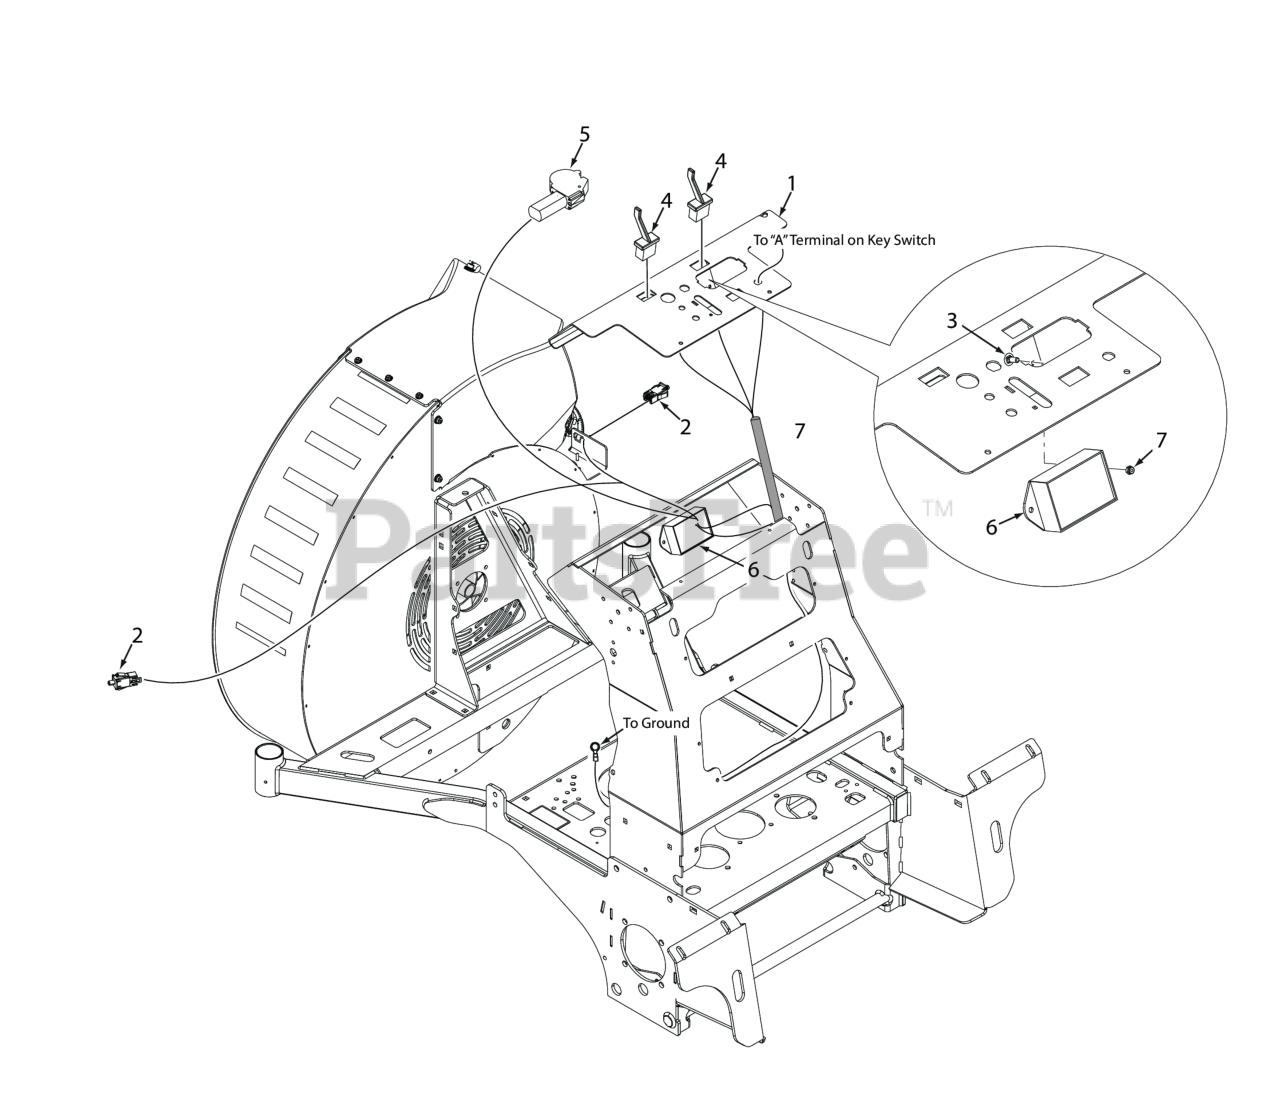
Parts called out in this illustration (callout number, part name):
1	Control Panel w/Decals
2	Plunger Switch, Single Pole
3	Bolt, Carriage #10-24 x 1/2"
4	Switch, Nozzle Direction
5	Motor, Gear Drive
6	Module, Nozzle Control
7	Nut, Elastic Stop #10-24
